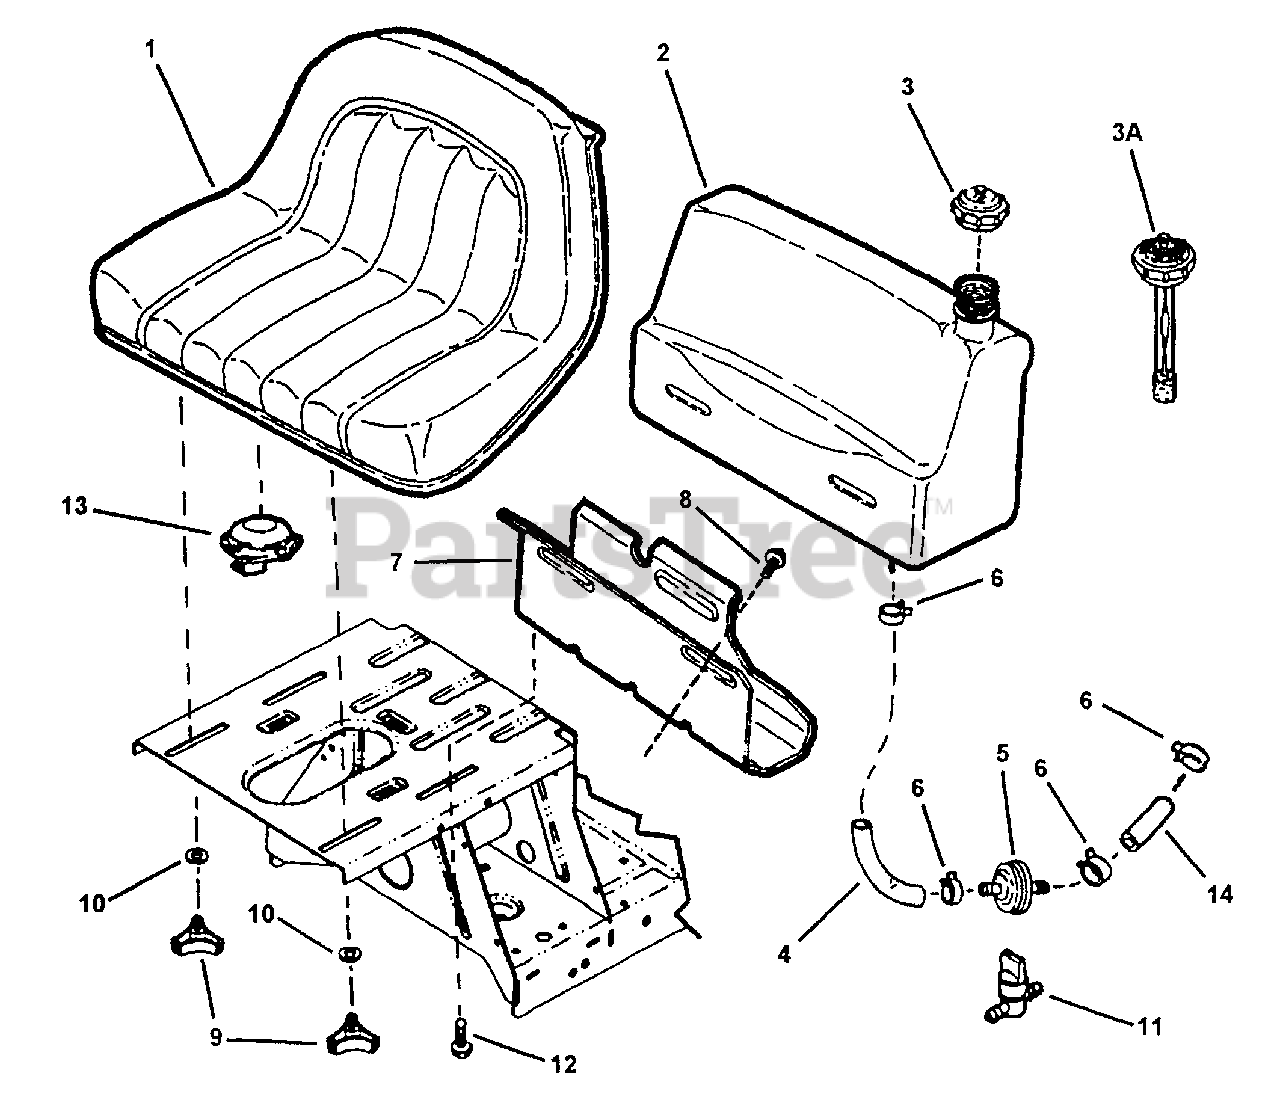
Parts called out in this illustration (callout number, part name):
1	SEAT, Operator
2	ASSEMBLY, Fuel Tank (28" Deck)
2	ASSEMBLY, Fuel Tank With Gauge
3	CAP, Fuel Tank
3A	CAP, Fuel Tank (With Gauge)
4	HOSE, Fuel (8-1/2" Long)
4	HOSE, Fuel (12-1/2" Long)
5	FILTER, Fuel (In-Line)
6	CLAMP, Fuel Line
7	BRACKET, Fuel Tank (Rear)
8	SCREW, 5/16-18 x 5/8" Pan Head Self-Tap
9	KNOB, Seat Adjusting
10	SPACER, 5/16
11	VALVE, Fuel Shut-Off
12	BOLT, 5/16-18 x 1/2" Hex Flange Lock w/Nylon Patch
13	SWITCH, Seat
14	HOSE, Fuel (3-1/2" Long)
